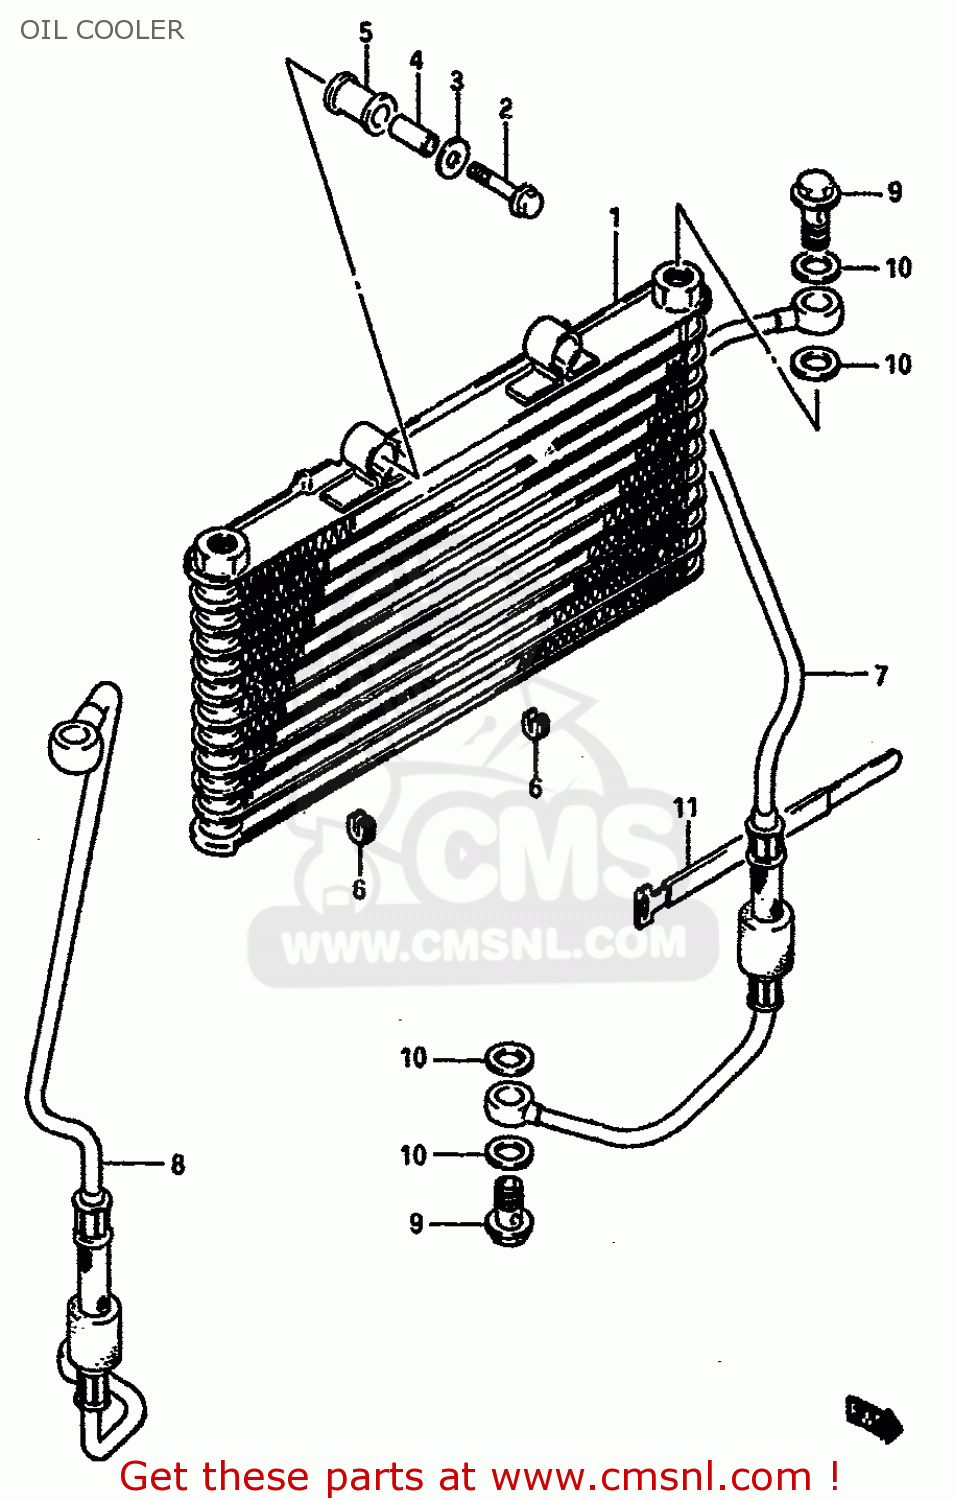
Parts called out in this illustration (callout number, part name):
1	COOLER ASSEMBLY,OIL
2	BOLT 8X40
3	WASHER(8.5X23X1.2)
4	SPACER (8.8X12X24.5)
5	CUSHION,OIL COOLER NO.1
6	CUSHION,OIL COOLER NO.2
7	HOSE,OIL
8	HOSE,OIL
9	BOLT,UNION
10	GASKET(16X22X2) (NAS)
11	CLAMP
